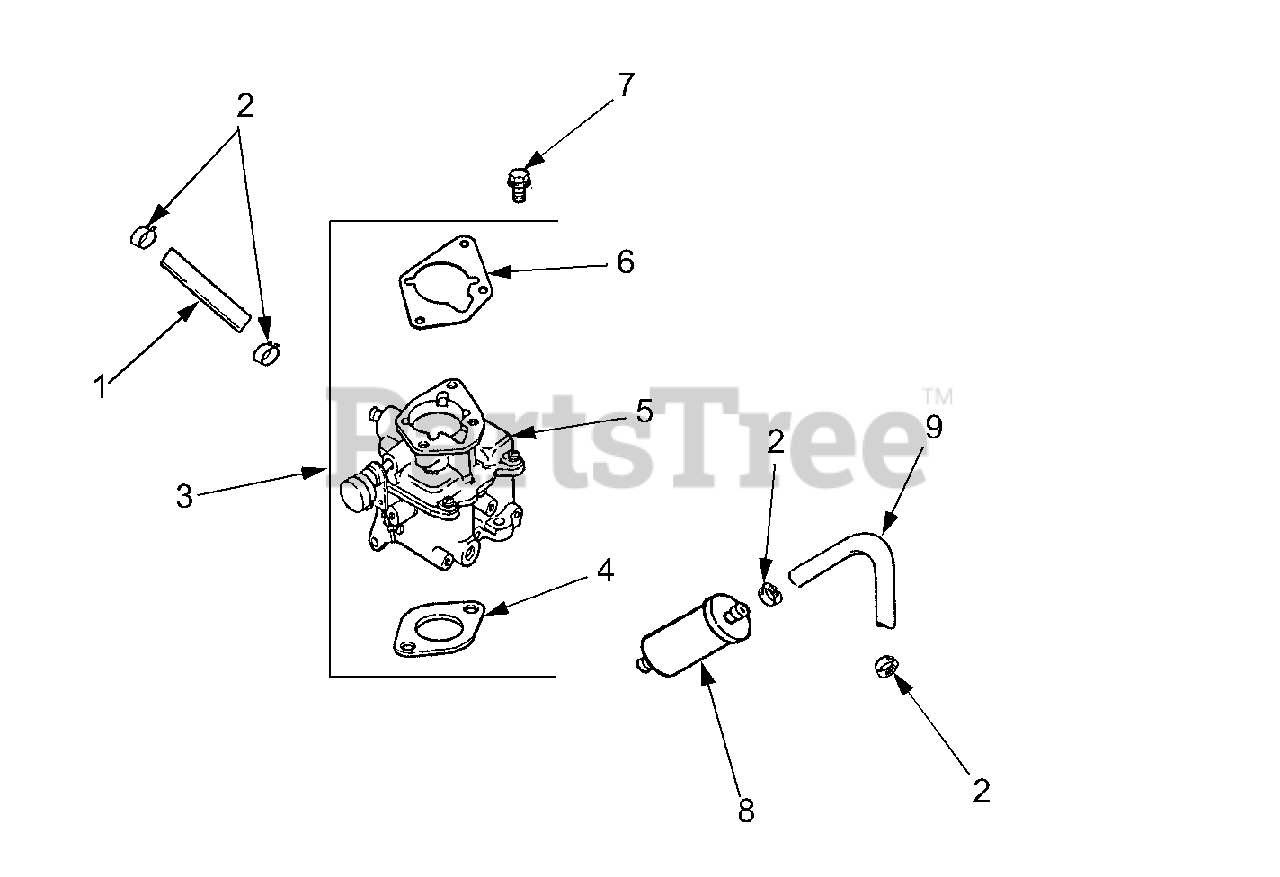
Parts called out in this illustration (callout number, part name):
1	Line, Fuel 10"
2	Clamp, Hose
3	Kit, Carburetor w/Gasket
4	Gasket, Carburetor
5	Carburetor Assembly
6	Gasket, Air Cleaner Base
7	Screw, Hex Flange
8	Filter, Fuel
9	Line, Fuel 11"
